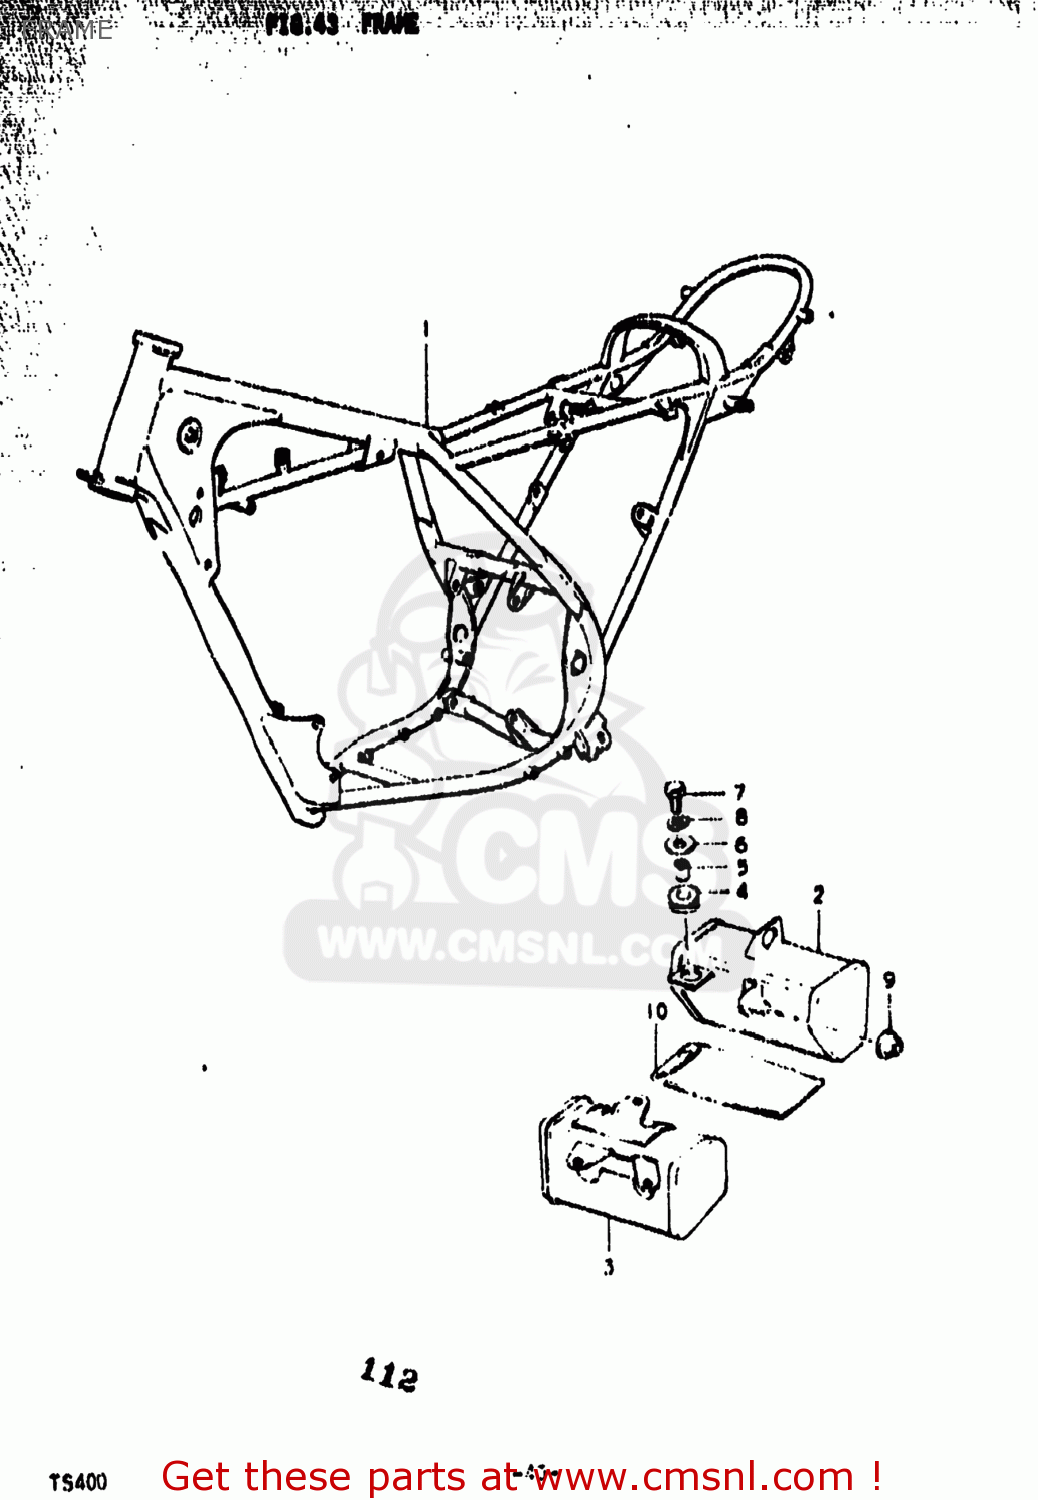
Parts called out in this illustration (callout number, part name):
1	FRAME
2	HOLDER,TOOL
3	HOLDER,TOOL
4	CUSHION
5	CUSHION
6	WASHER (6.5X20X1.2)
7	BOLT(6X20)
8	LOCK WASHER
9	CUSHION
10	TOOL ASSY
